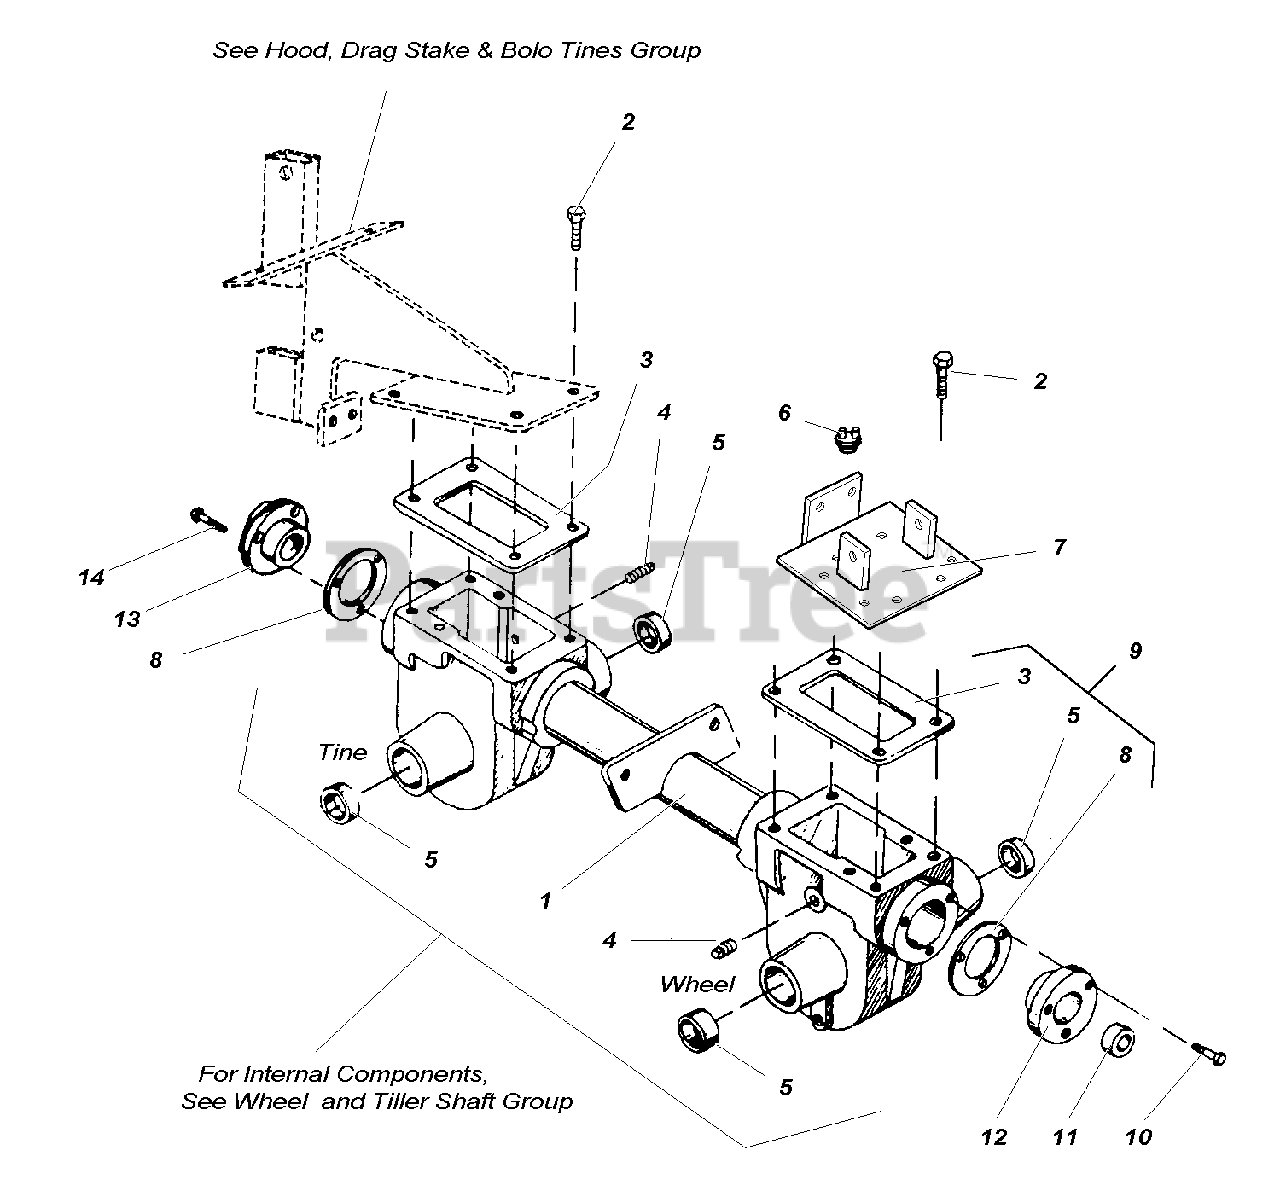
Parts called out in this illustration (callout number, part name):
1	TRANSMISSION ASSEMBLY
2	CAPSCREW, Hex Flange Head, 5/16"-18 x 3/4"
3	GASKET, Housing & Transmission Cover
4	PLUG, Pipe Socket Head 1/4"-18, Oil Check
5	SEAL, Housing
6	PLUG, Oil Fill
7	COVER, Transmission Wheel Housing
8	GASKET, Bearing Cap Front, Rear
9	GASKET KIT, Oil Seal (Includes Ref. Nos. 3, 5 and 8)
10	CAPSCREW, Hex Flange Head, 1/4"-20 x 3/4"
11	SEAL, Oil Drive Shaft
12	CAP, Front Bearing
13	CAP, Rear Bearing
14	CAPSCREW, Hex Flange Head, 1/4"-20 x 7/8"
